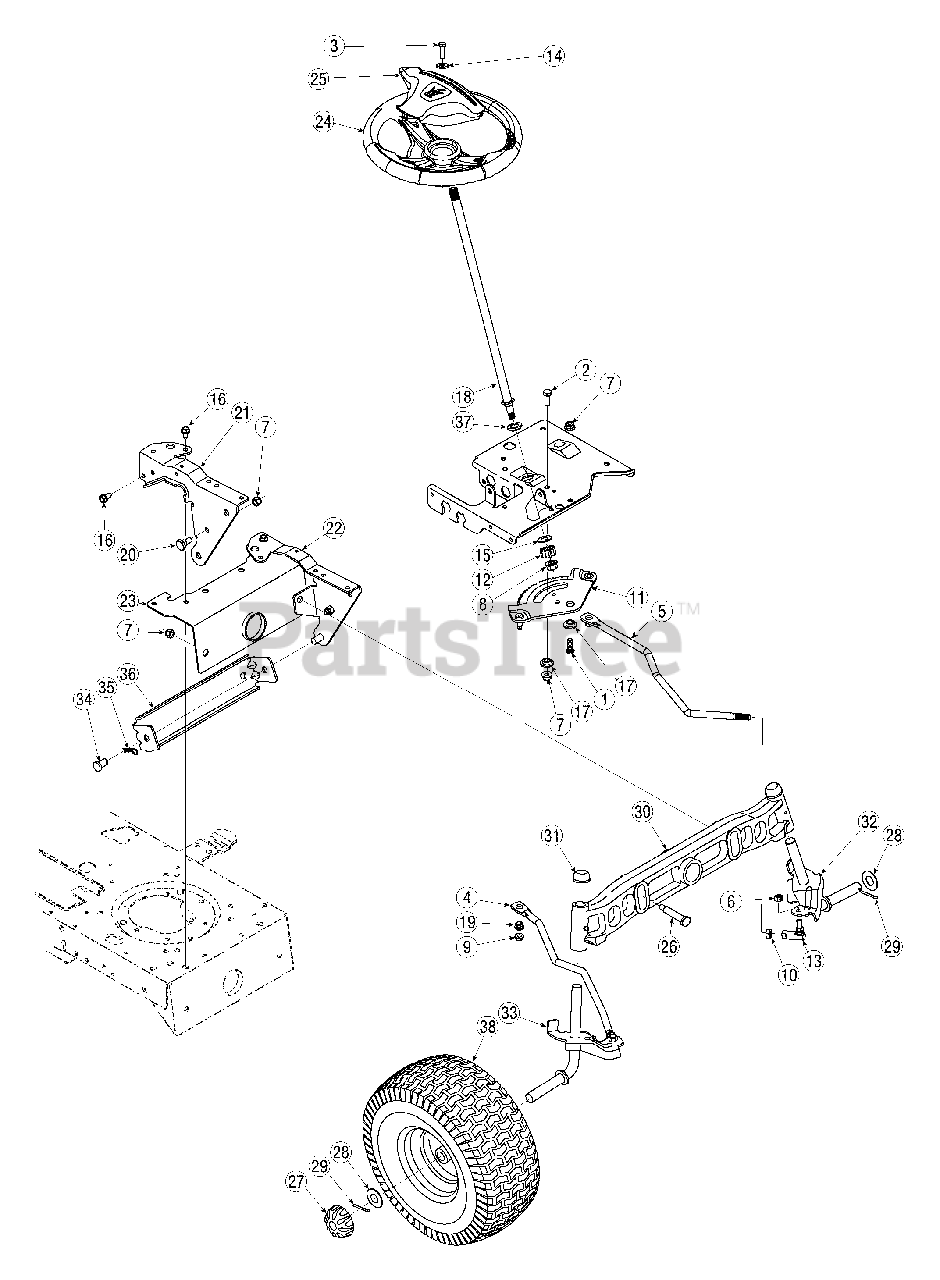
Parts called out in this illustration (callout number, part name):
1	Hex Screw, 3/8-16, 1.00, Gr5
2	Hex Screw, 3/8-16, 1.00, Gr5
3	Hex Screw, 5/16-18, 1.00, Gr5
4	Link, Drag, RH
5	Link, Drag, LH
6	Nut, Hex Lock, 3/8-24
7	Nut, Flange Lock, 3/8-16, Grf, Nylon
8	Nut, Flange Lock, 7/16-20
9	Nut, Flange Lock, 5/16-18, Gr5
10	Nut, Jam, 7/16-20, Gr2
11	Gear, Steering, 11/90 Ratio
12	Gear, Pinion, Steering
13	Ball Joint, 7/16-20, Lock
14	Washer, Flat,.406 x.875 x.105
15	Washer, Flat,.51 x 1.12 x.06
16	Screw, 5/16-12, 0.750
17	Spacer, Shoulder,.38 x 1.00 x.31
18	Shaft, Steering,.625 OD x 24.25 Lg
19	Plastic Bushing.380 ID
20	Screw, Shoulder,.498 x.340, 3/8-16
24	Steering Wheel, 3 Spoke, Soft Grip
25	Steering Wheel Cover
26	Shlder Screw,.5 x 2.2, 3/8-16
27	Deluxe Hub Cap
28	Flat Washer,.78 x 1.589 x.06
29	Cotter Pin, 5/32 x 1.25
30	Cast Iron Pivot Bar
31	Push Cap
32	LH Axle Assembly,.750
33	RH Axle Assembly,.750
34	Pin, Clevis,.50 x.78
35	Cotter Pin, Inter,.080 x 1.5625
37	Hex Flange Bearing
